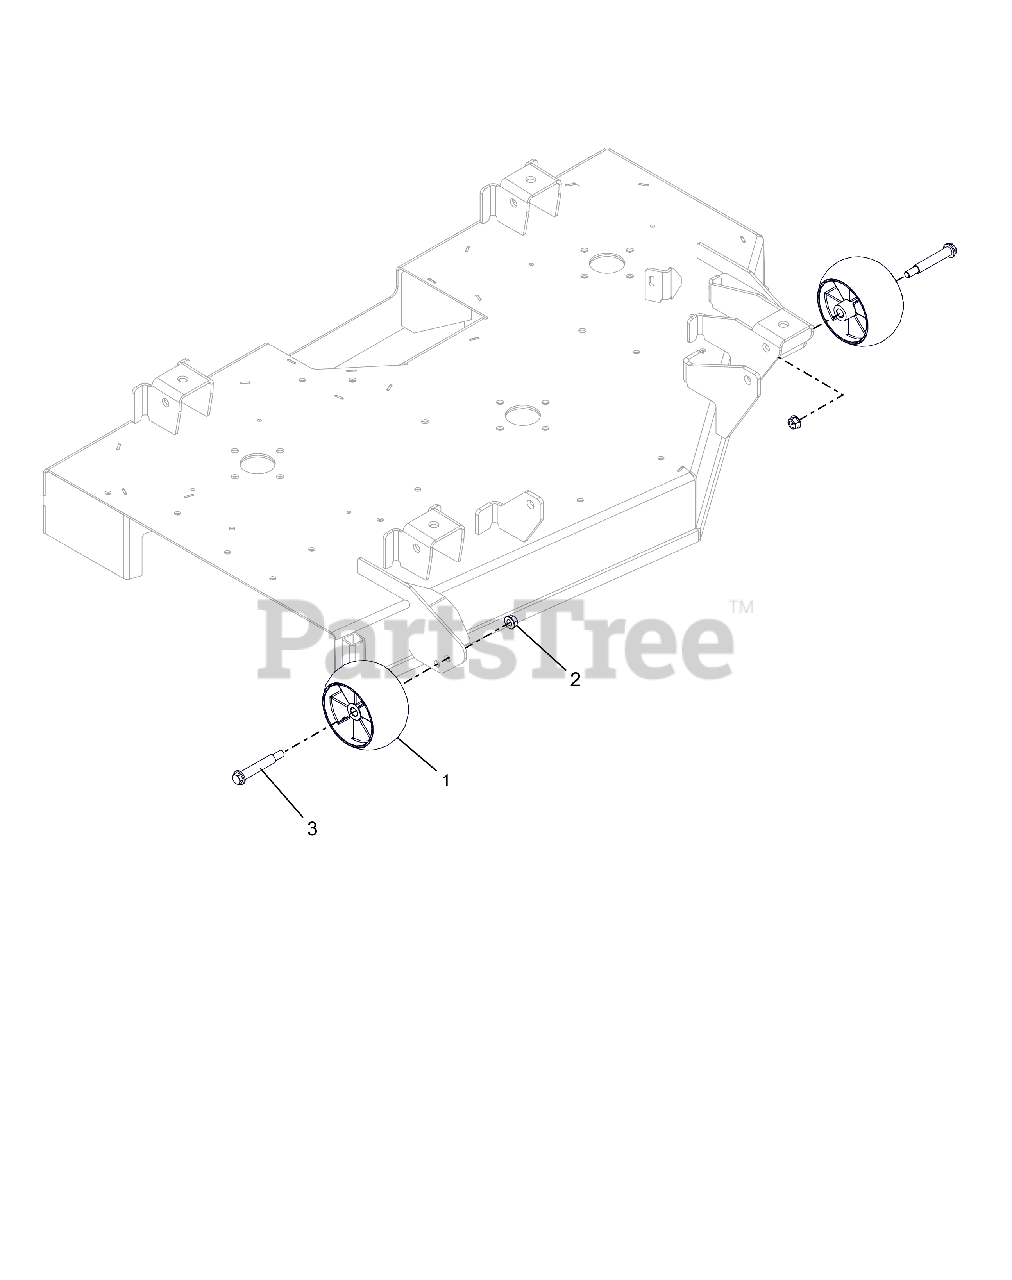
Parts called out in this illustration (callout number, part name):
1	ANTI-SCALP WHEEL - 5X OS
2	NUT-LK-TOP-FLG .38-16 ZC120
3	BLT-SHLDR .38-16X2.50 HWH G5
